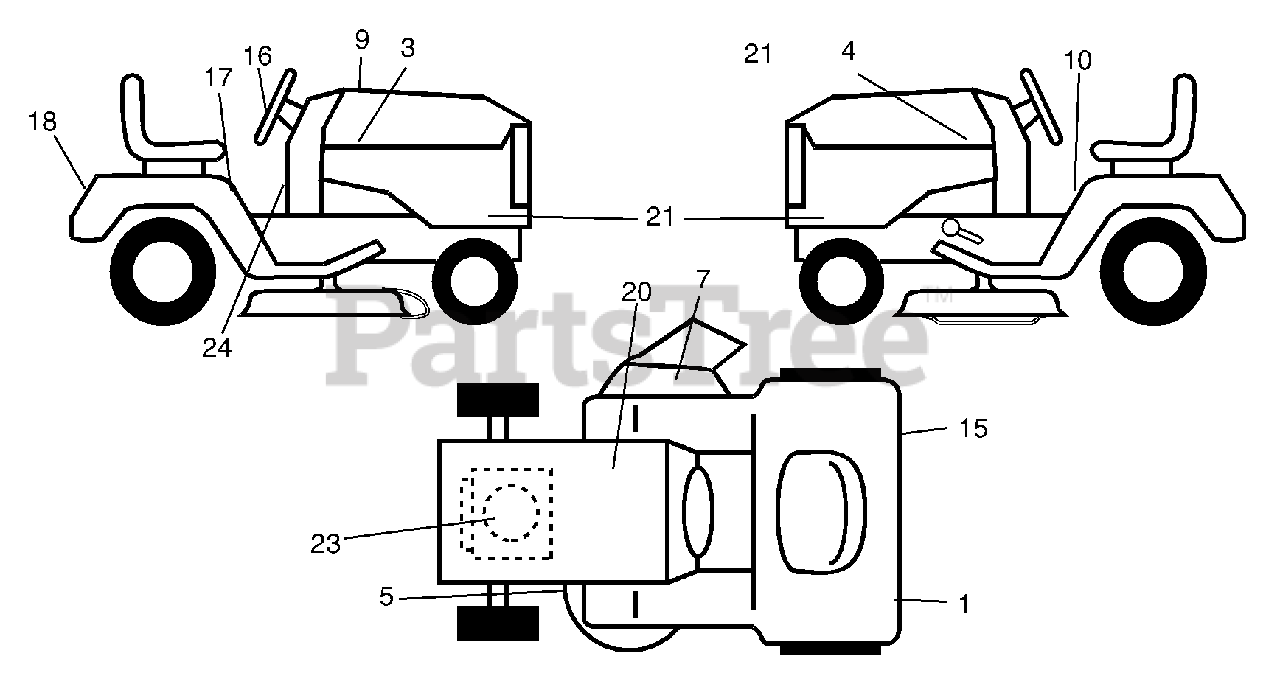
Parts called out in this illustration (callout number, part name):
1	Reflector, LH
3	Decal, Hood RH
4	Decal, Hood LH
5	Decal, Deck Sch.
7	Decal, Deck "B" "42"
9	Decal, Replacement Hood
10	Decal, Fender, Danger
15	Decal, Reflector, RH
16	Decal, Steering Wheel
17	Decal, Fender, Operator Instructions
18	Decal, Fender
20	Decal, Battery
21	Decal, Hood, Side Panel
23	Decal, Engine
24	Decal, Dash
